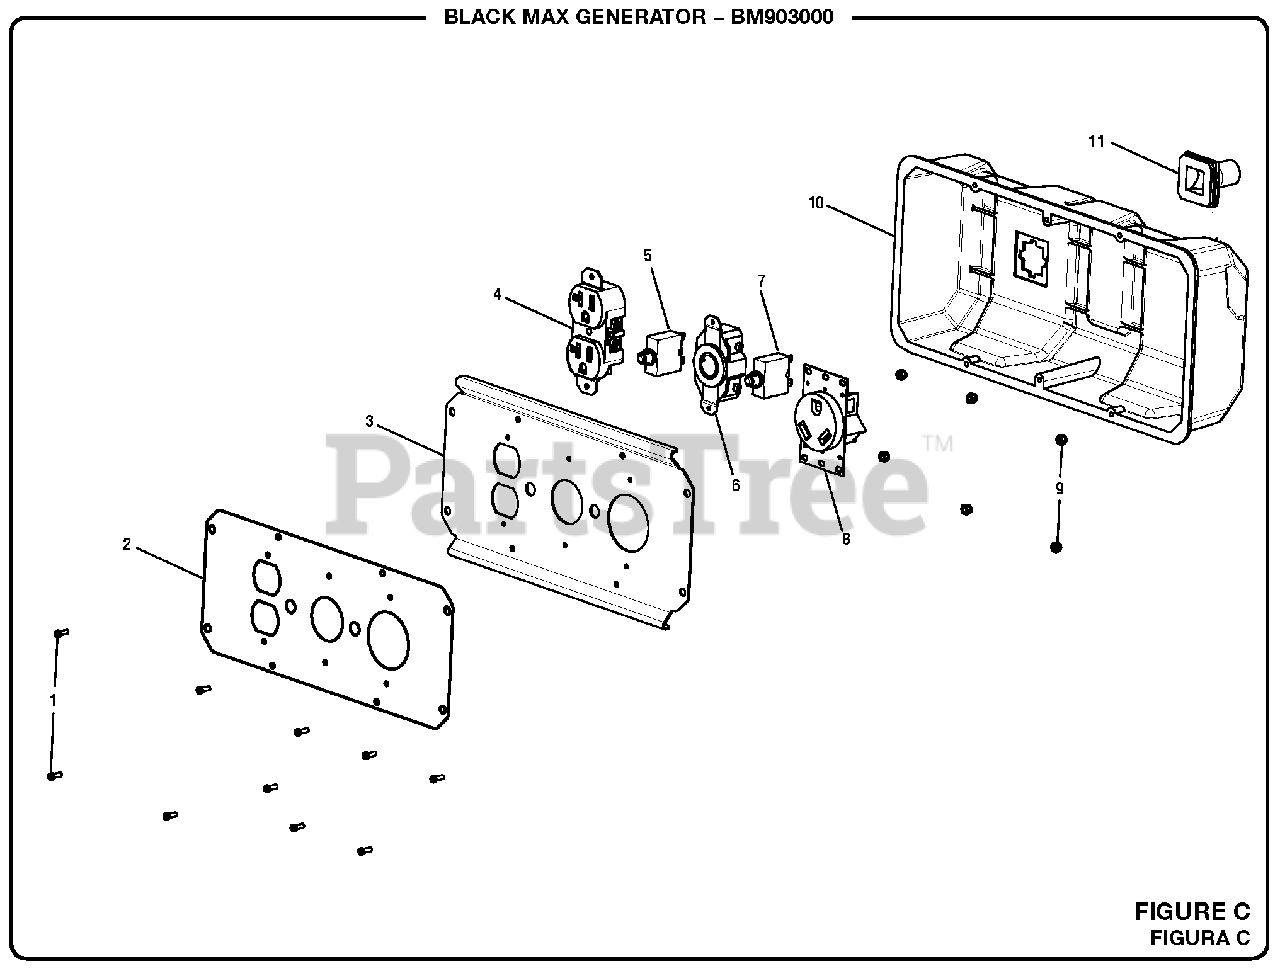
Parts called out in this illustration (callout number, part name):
1	Screw (6-20 x 38 in)
2	Control Panel Label
3	Control Panel Faceplate
4	120 Volt Duplex Receptacle
5	Circuit Breaker (20A)
6	120 Volt Receptacle (30A)
7	Circuit Breaker (25A)
8	120 Volt RV Receptacle (30A)
9	Nut (6-32)
10	Control Box (Back Panel)
11	Rubber Sleeve
